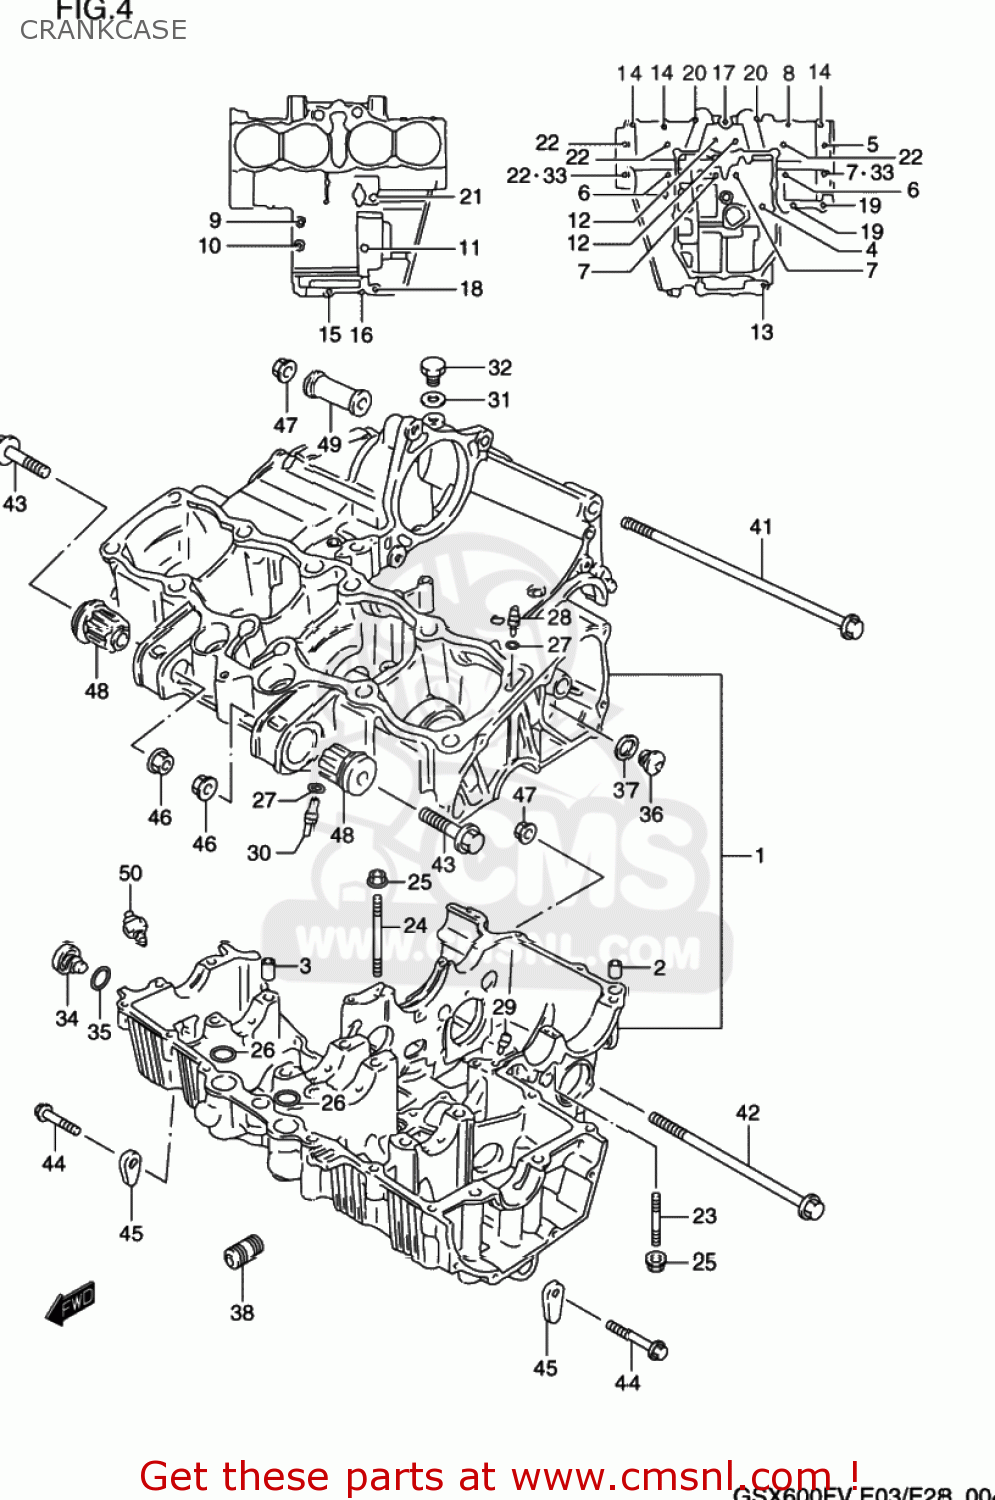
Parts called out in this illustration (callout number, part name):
1	CRANKCASE SET
2	PIN(10.4X13X22)
3	PIN(8.4X11X20)
4	BOLT(6X105)
5	BOLT(8X105)
6	BOLT(8X125)
7	BOLT(8X115)
8	BOLT
9	BOLT
10	BOLT,CL.COVER
11	BOLT
12	BOLT
13	BOLT
14	BOLT
15	BOLT
16	BOLT
17	BOLT
18	BOLT
19	BOLT, HYDRAULIC UNIT NO.2
20	BOLT
21	BOLT
22	BOLT(8X95)
23	STUD BOLT
24	STUD BOLT
25	NUT
26	O RING(D:2.5,ID:21)
27	O RING(D:1.2,ID:4)
28	JET,AIR
29	JET
30	JET,OIL GALLERY
31	GASKET(12.1X16.2X3.7) (NAS)
32	PLUG(12X9)
33	GASKET(8.5X17X2.3) (NAS)
34	PLUG
35	O RING(D:2.4,ID:16.8)
36	PLUG
37	GASKET(13.8X18.8X4.8) (NAS)
38	UNION,OIL STAND
39	PLATE,CRANK THRUST
40	PLATE,CRANK THRUST
41	BOLT(10X175)
42	BOLT(10X130)
43	BOLT
44	BOLT
45	NUT
46	NUT
47	NUT
48	BUSH,ENGINE MOUNTING
49	SPACER,ENGINE MOUNT(L27)
50	SWITCH ASSEMBLY,OIL PRESSURE
